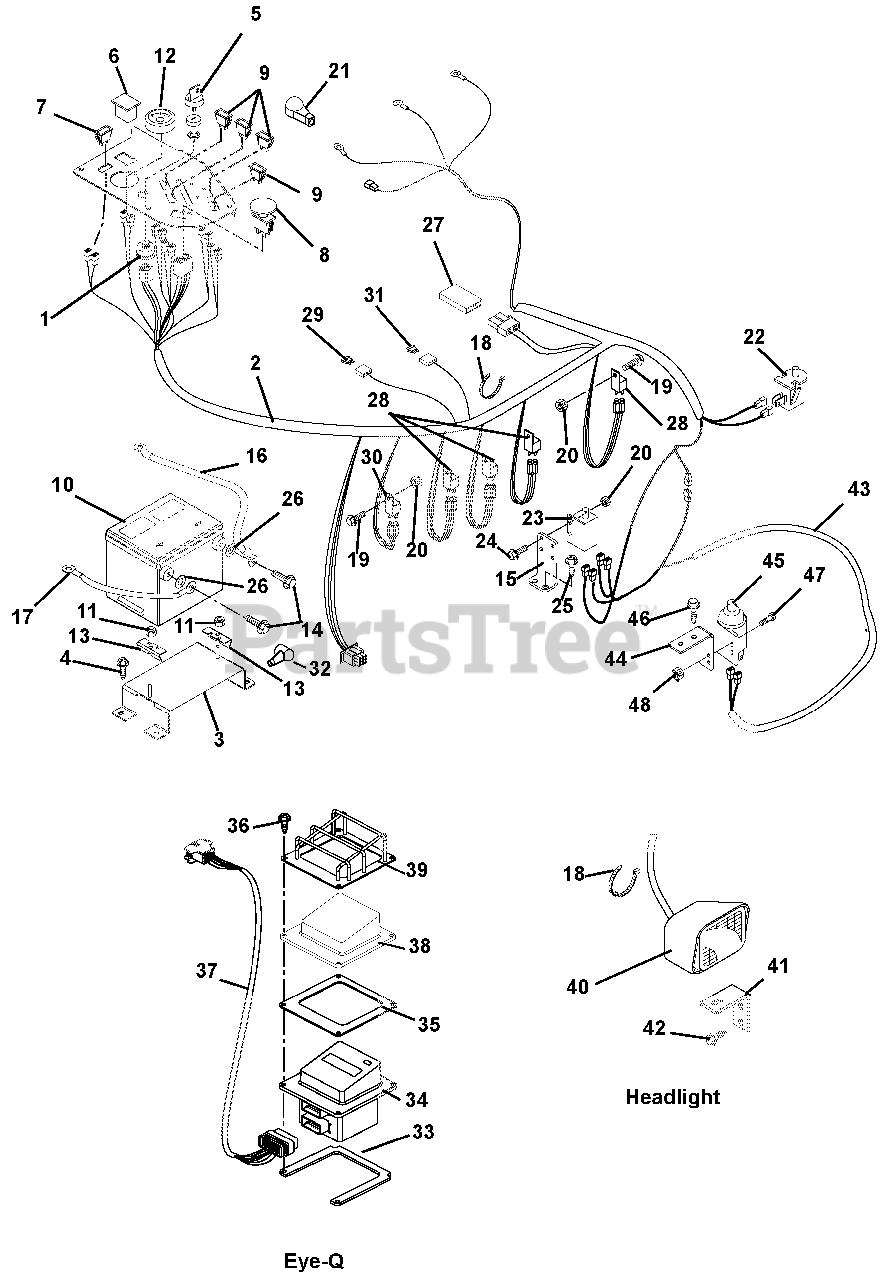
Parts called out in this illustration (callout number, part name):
1	Switch, Ignition
2	Harness, Wiring
3	Weldment, Battery Support
4	Screw-Tapping .38-16 x .75 Hex Washer Head
5	Key-with Cap
6	Hour Meter
7	Switch, Light
8	Switch-Clutch With Retainer Ring
9	Light-Indicator
10	Battery with Tube
11	Nut-Locking-Top-Flange .31-18
12	Gauge, Temperature
13	Bracket, Battery Hold-Down
14	Bolt-Hex .25-20 x .75 Grade 5
15	Mount, Safety Switch
16	Positive Cable
17	Cable, Negative Battery
18	Cable Tie
19	Screw-Machine 10-24 x .75 Hex Washer Head
20	Nut-Locking-Nylon 10-24 With Insert
21	Boot, Terminal, Red
22	Switch, Snap Mounting (N.O.) (Included with Seat)
23	Switch-Single Pole
24	Screw-Machine 10-24 x .75 Hex Washer Head
25	Screw-Tapping .25-20 x .50 Hex Washer Head
26	Washer-Flat-Steel .406 x 1.00 x ..083
27	Diode, Connector Shell
28	Relay (Included with Harness)
29	Fuse, ATO 30 Amp (Included with Harness)
30	Pre-Heat Timer (Included with Engine)
31	Fuse, ATO 60 Amp (Included with Harness)
32	Battery Terminal Boot, Red
33	Spacer, Enclosure Mounting (Bottom)
34	Assembly, Eye-Q - Enhanced
35	Gasket, Eye-Q
36	Screw, Machine 10-24 x 1.0 Slotted Pan Black
37	Harness Jumper (Eye-Q)
38	Guard, Element
39	Guard, Eye-Q
40	Headlight
41	Bracket, Headlight Mounting
42	Screw, Tapping, .38-16 x .50 Hex Washer Head
43	Harness, Wire Adapter, CE
44	Switch, Mount
45	Switch, Single Pole (N.O.) with Cover
46	Screw,Tapping .31-18 x .50 Hex Washer Head
47	Screw, Machine 10-24 x .75 Hex Washer Head
48	Nut, Locking, Nylon 10-24 with Insert
